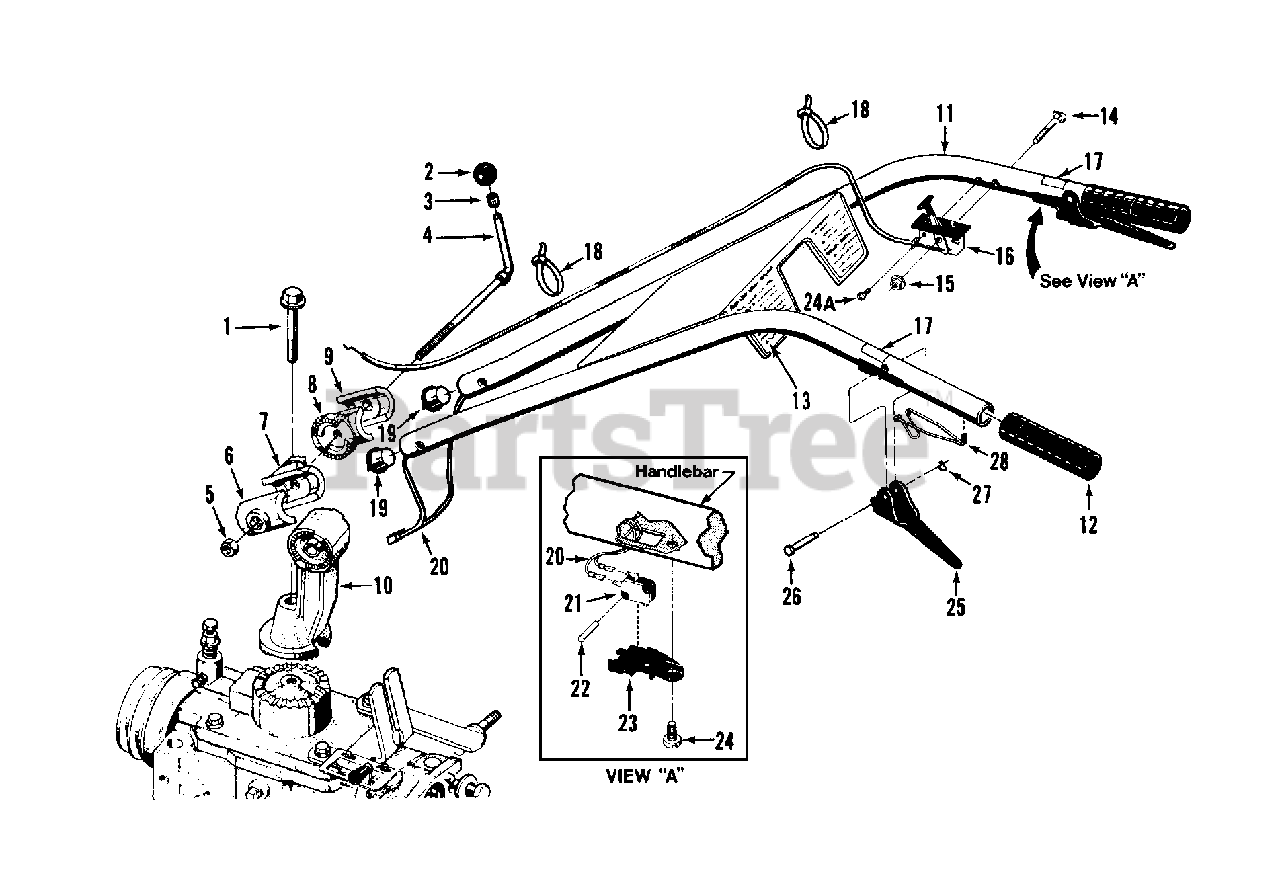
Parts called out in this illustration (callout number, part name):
1	Bolt-Hex hd., flanged self-locking Grade 5, 1/2-13 x 3-1/2"
2	Knob-handlebar height adjustment
3	Ring-retaining (tolerance ring)
4	Stud-handlebar height adjustment
5	Nut-hex, 1/2"-13
6	Clamp-left, handlebar height adjustment
7	Ratchet-left, handlebar height adjustment
8	Ratchet-right, handlebar height adjustment
9	Clamp-right, handlebar height adjustment
10	Base-handlebar mounting
11	Handlebars
12	Grip-handlebars
13	Decal-Control panel
14	Bolt-curved hd, GR5, 1/4-20 x 2"
15	Nut-hex, flanged self-locking, whiz lock, 1/4"-20
16	Throttle Control & Cable
17	Decal-Forward Interlock Lever
18	Tie-plastic
19	Plug-wire harness retainer
20	Handlebar Wire Harness Assy-forward interlock system
21	Handlebar Switch-forward interlock system
22	Lock Pin-handlebar switch
23	Switch Housing-handlebar switch
24	Screw-pan head, 10-24 x 1/2", thread-forming
24A	Screw-phillips head, 10-32 x 1/2", thread-forming
25	Lever-forward interlock
26	Pivot Pin-forward interlock lever
27	Retaining Ring-klip ring-forward interlock lever
28	Return Spring-fwd interlock lever
